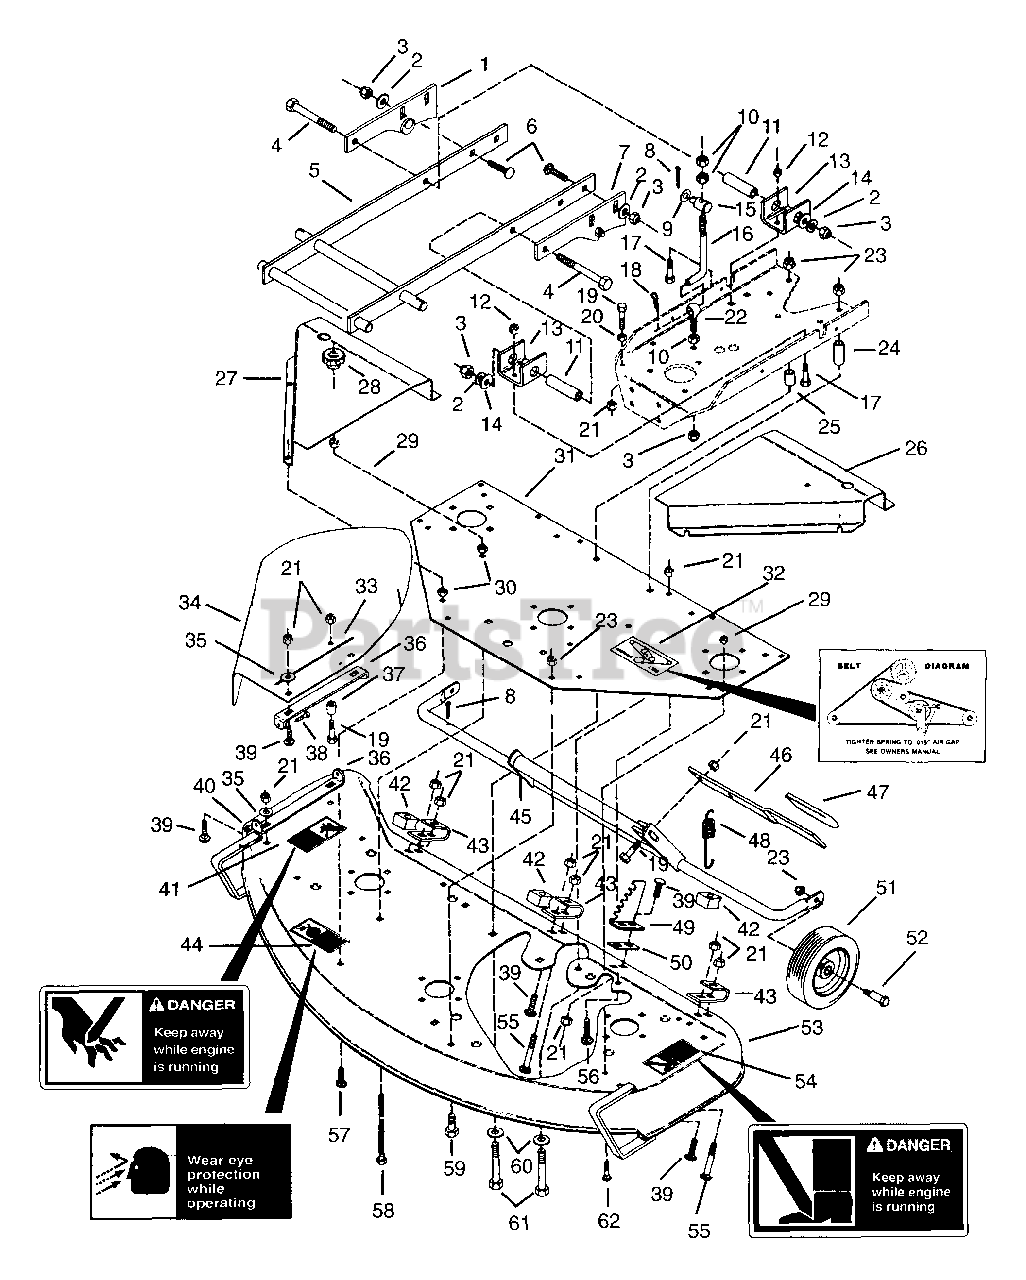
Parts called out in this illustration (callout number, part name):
1	Weldment, Deck Leveling Right Hand
2	Washer-Flat-Steel .531 x 1.250 x .100
3	Nut-Locking .50-13
4	Bolt-Hex .50-13 x 3.25 Grade 5
5	Weldment, Pivot Arm
6	Bolt-Round Head Square Neck .50-13 x 1.25
7	Weldment, Deck Leveling Left Hand
8	Pin-Cotter .12 x 1.25
9	Washer-Flat-Steel .531 x 1.000 x .063
10	Nut-Jam .50-13 Grade 2
11	Spacer .510 x .750 x 2.02 Steel
12	Nut-Locking .312-18
13	Support, Mower Pivot
14	Washer-Flat-Steel .813 x 1.370 x .100
15	Pivot, Mower Lift
16	Rod, Lift
17	Bolt-Hex .31-18 x .88 Grade 5
18	Pin-Cotter .12 x 2.0
19	Bolt-Hex .38-16 x 1.50 Grade 5
20	Nut-Jam .375-16
21	Nut-Locking-Nylon .375-16 Grade 2
22	Bolt, Eye
23	Nut-Locking-Nylon .50-13 Grade 5
24	Spacer .510 x .840 x 2.437 Steel
25	Rod, PTO Control
26	Cover, Pulley Left Hand
27	Cover, Pulley Right Hand
28	Knob
29	Nut-Locking-Nylon .312-18 Grade 2
30	Nut-Jam .312-18
31	Plate, Support
32	Decal, Belt Installation
33	Stripe
34	Shield, Safety External 50" Mower
35	Washer-Flat-Steel .406 x .812 x .065
36	Bracket, Chute
37	Bushing-Sleeve .407 x .625 x .750
38	Bolt-Hex .25-20 x .875
39	Bolt-Round Head Square Neck .38-16 x 1.0
40	Nut-Locking-Nylon .250-20 Grade 2
41	Decal, Danger Hand
42	Stop, Nylon
43	Bracket, Axle Support
44	Decal, Warning Eye
45	Weldment, Axle Pivot
46	Lever, Height of Cut
47	Grip, Handle
48	Spring-Tension .095 x .85 x 4.38
49	Bracket, Height Adjustment
50	Shim, Mower Height Adjuster Bracket
51	Tire/Wheel Assembly 6 x 2
52	Bolt, Eccentric
53	Weldment, 50" Mower Deck
54	Decal, Danger Foot
55	Bolt-Round Head Square Neck .38-16 x 2.00
56	Bolt-Round Head Square Neck .375-16 x .75 Grade 1
57	Bolt-Round Head Square Neck .31-18 x 1.12
58	Bolt-Round Head Square Neck .31-18 x 3.5
59	Bolt-Hex .50-13 x 1.25 Grade 5
60	Washer-Flat-Steel .531 x 1.062 x .095
61	Bolt-Hex .50-13 x 3.75
62	Bolt-Round Head Square Neck .31-18 x .75
